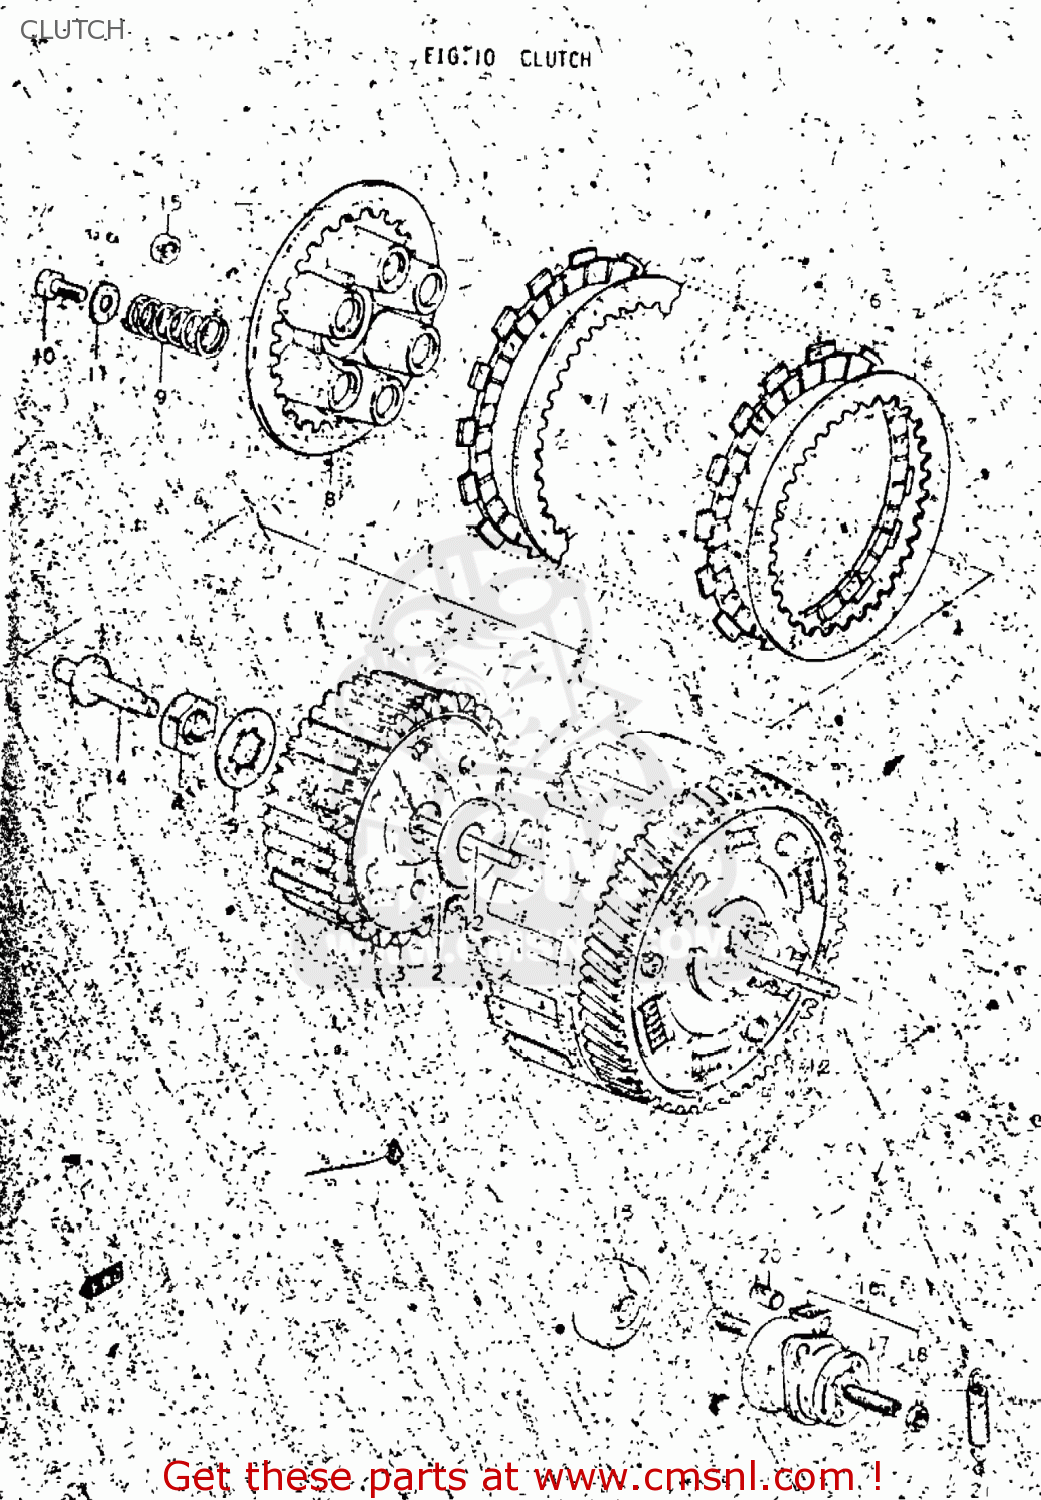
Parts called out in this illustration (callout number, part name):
1	GEAR ASSEMBLY,PRIMARY DRIVE
2	WASHER(20X44X3)
3	HUB,CLUTCH SLEEVE
4	NUT (20MM)
5	WASHER,LOCK
6	PLATE,CLUTCH DRIVE (MCA)
7	PLATE,CLUTCH DRIVEN(T:2.0) (NAS)
8	DISC,CLUTCH PRESSURE
9	SPRING
10	BOLT
11	WASHER
12	RACK,CLUTCH RELEASE
13	BEARING(15X28X2)
14	WASHER
15	E RING 12MM
16	PINION,CLUTCH RELEASE
17	OIL SEAL
18	BOLT(6X12)
19	WASHER
20	ARM,CLUTCH RELEASE
21	BOLT
22	WASHER
23	NUT
24	SPACER
25	BEARING
26	PIN
